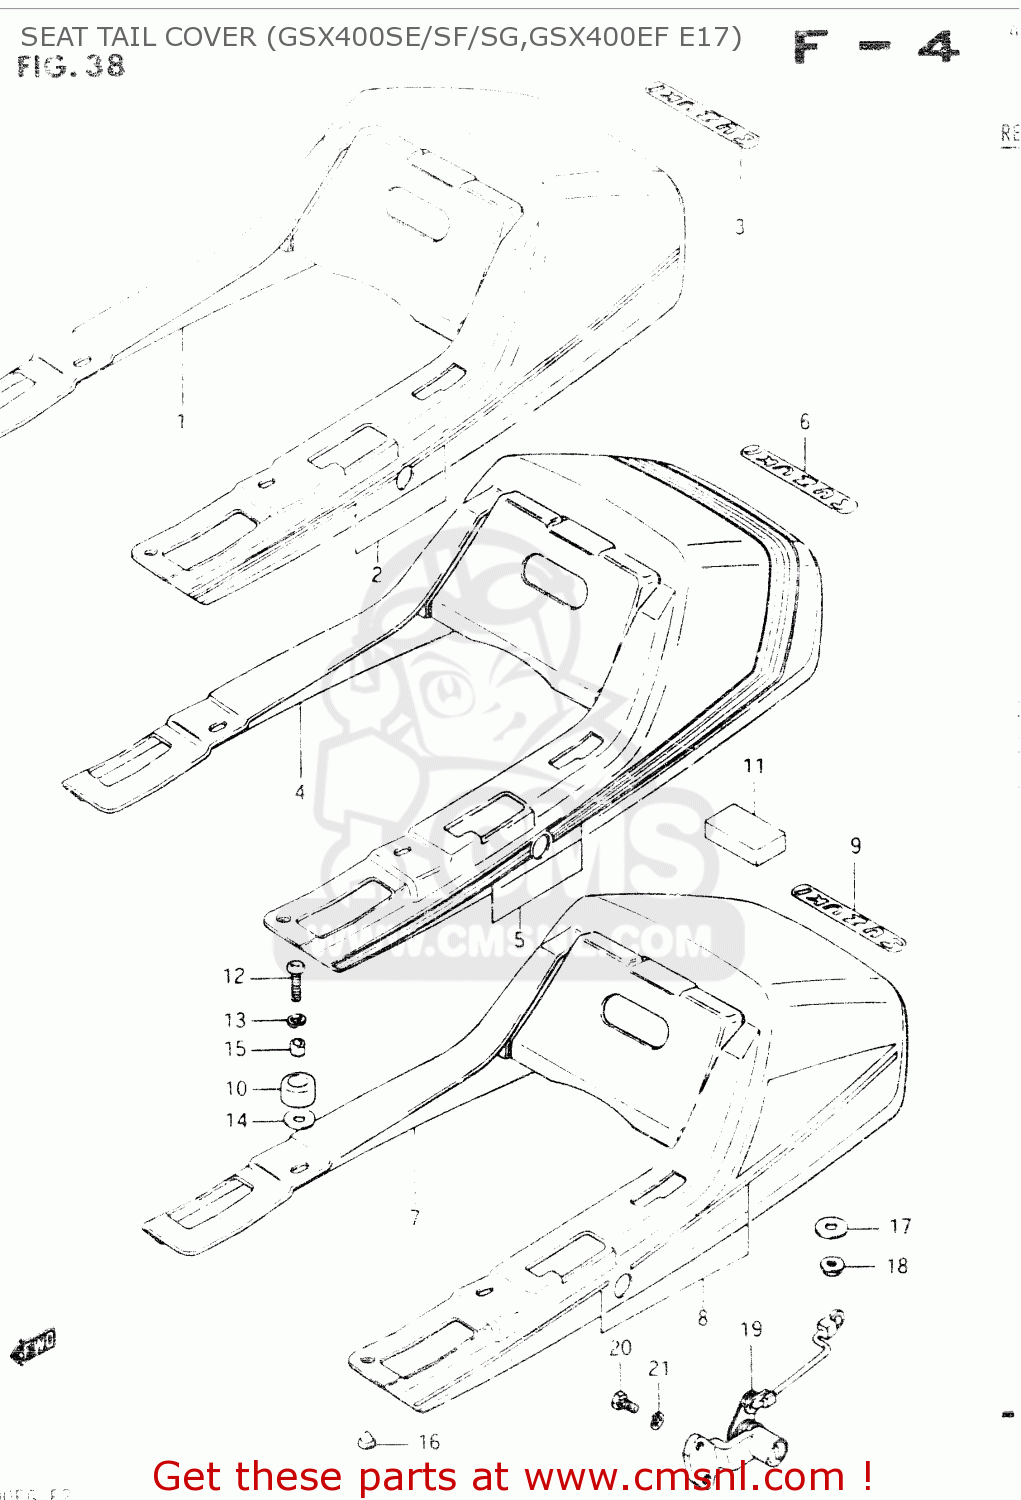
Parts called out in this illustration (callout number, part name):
1	COVER, SEAT TAIL
2	TAPE SET, SEAT TAIL COVER
3	EMBLEM
4	COVER, SEAT TAIL
5	TAPE SET, SEAT TAIL COVER
6	EMBLEM
7	COVER, SEAT TAIL
8	TAPE SET, SEAT TAIL COVER
9	EMBLEM(WHITE)
10	CUSHION,COVER
11	CUSHION
12	SCREW
13	WASHER,LOCK
14	WASHER (6.5X24X1.6)
15	SPACER
16	CUSHION
17	WASHER
18	WASHER
19	LOCK ASSEMBLY,SEAT
20	BOLT
21	LOCK WASHER
